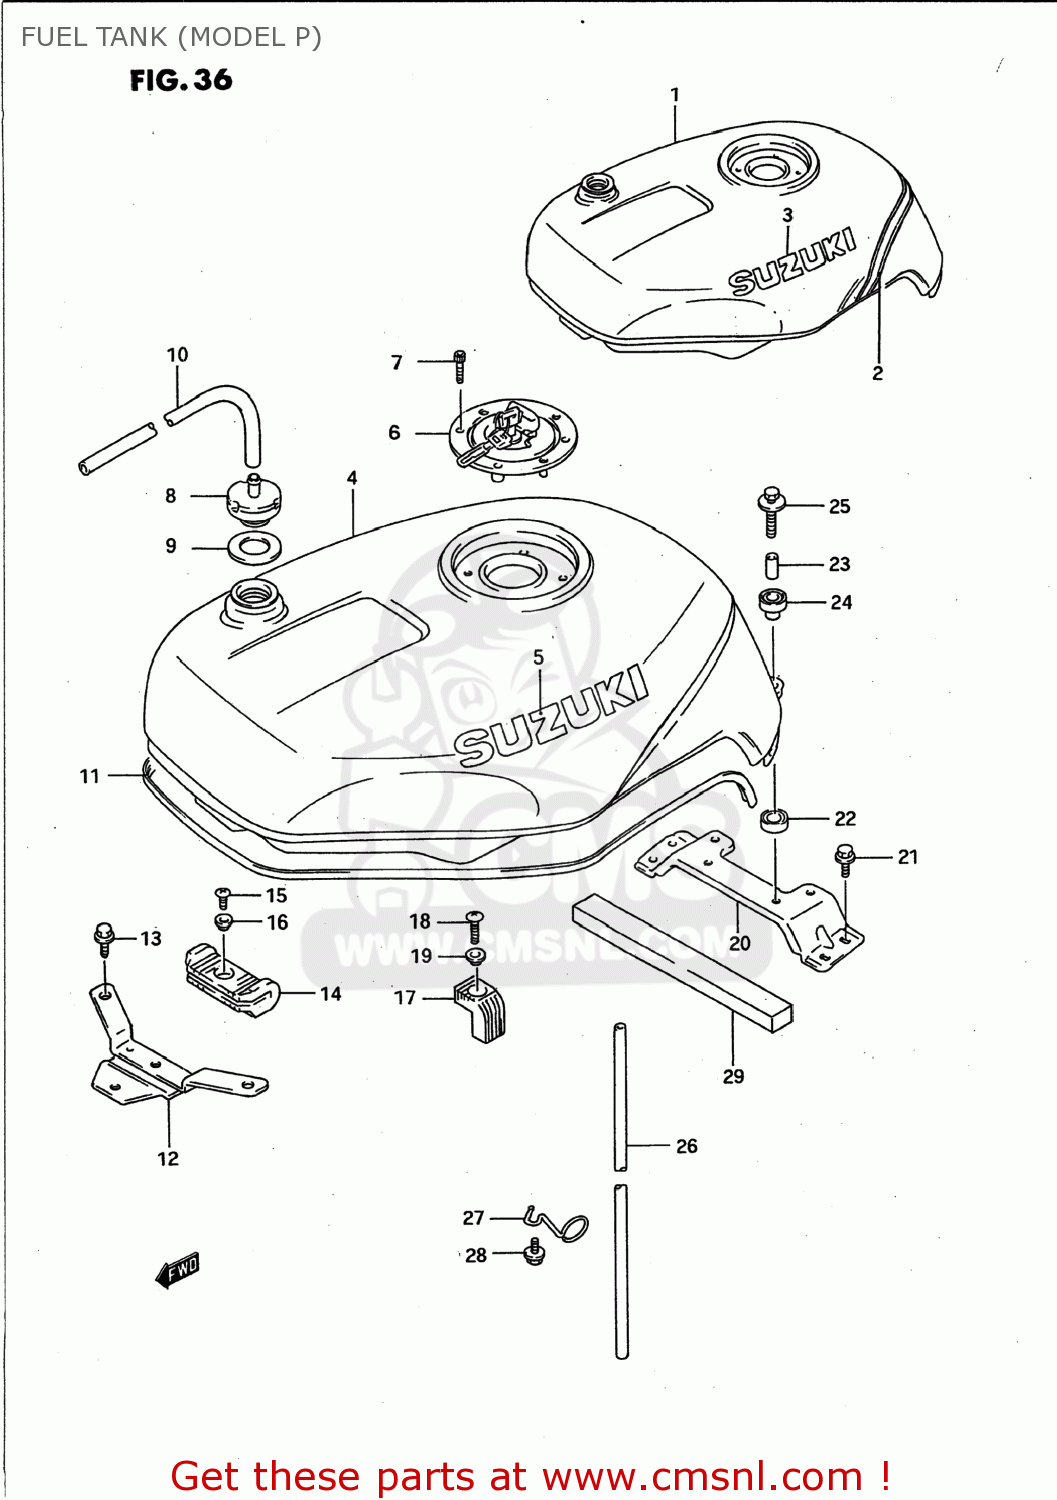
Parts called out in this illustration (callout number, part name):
1	TANK ASSEMBLY,FUEL
2	TAPE,FUEL TANK
3	EMBLEM,FUEL TANK
4	TANK ASSEMBLY,FUEL
5	EMBLEM,FUEL TANK
6	CAP SET,FUEL TANK
7	BOLT(5X20)
8	PLUG,FUEL TANK BREATHER
9	GASKET 27X40X2.5 (NAS)
10	HOSE(5X8.2X600)
11	MOLDING,FUEL TANK
12	BRACKET,FUEL TANK,FRONT
13	BOLT
14	CUSHION,FUEL TANK FR
15	SCREW 5X10
16	WASHER
17	CUSHION,FUEL TANK
18	SCREW
19	WASHER
20	BRACKET,FUEL TANK,REAR
21	BOLT
22	CUSHION
23	SPACER
24	CUSHION
25	BOLT
26	HOSE
27	GUIDE,DRAIN HOSE
28	BOLT
29	CUSHION,AIR SEAL
